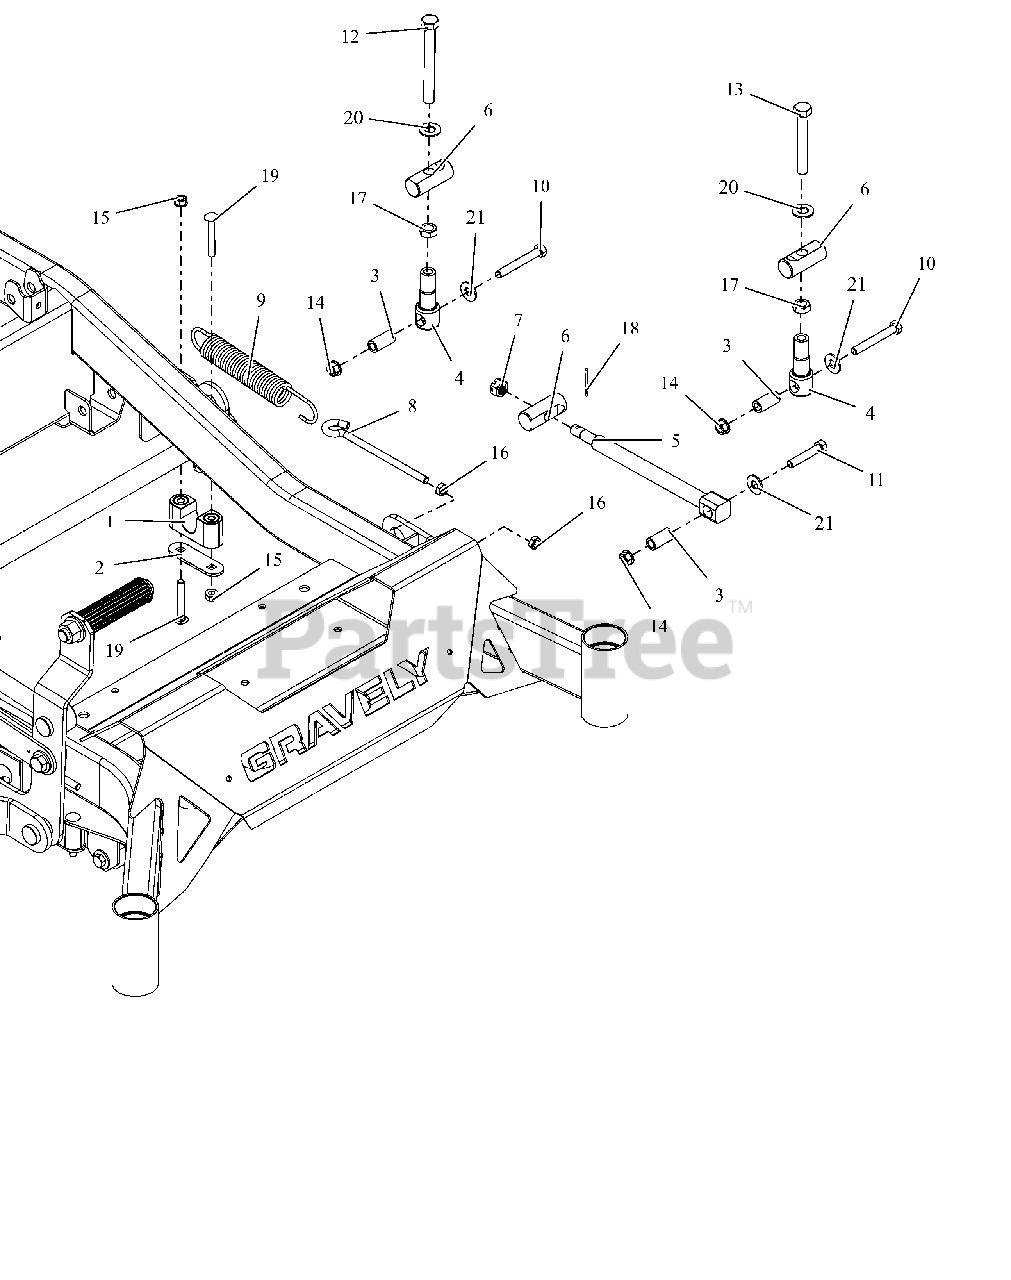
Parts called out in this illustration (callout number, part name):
1	ASM-BUSHING, DECK LIFT
2	PLATE, BEARING SUPPORT
3	SPACER, DECK LEVELING
4	LINK, DECK LIFT FORMED
5	DRAG,LINK-HD
6	PIN, DECK LIFT
7	NUT-SL .50-13
8	BOLT,.38-16 X 5.25-.62 DIA EYE
9	SG-TENS .162X1.25X8.25 WLD 25
10	BLT, HEX .38-16X2.75 G8 ZCC
11	BLT,HEX .38-16X2.00 G5 ZCC
12	BLT, HEX .50-13X4.50F G8 ZCC
13	BLT, HEX 0.5-13X3.5F GR5 ZCC
14	NUT-LK-TOP-FLG .38-16 ZC120
15	NUT,LK-CTR-FLG .31-18 GF ZCC
16	NUT-JAM .375-16 G2 ZCC
17	NUT-JAM .500-13 G2 ZCC
18	PIN,CTR.12X1.25EXTPRSQCT ZC120
19	BLT, RHSSN.31-18X2.25 G5 ZCC
20	WSHR, FLT .557X1.040X.102 ZCC
21	WSHR,FLT .438X1.00X.083 ZCC
